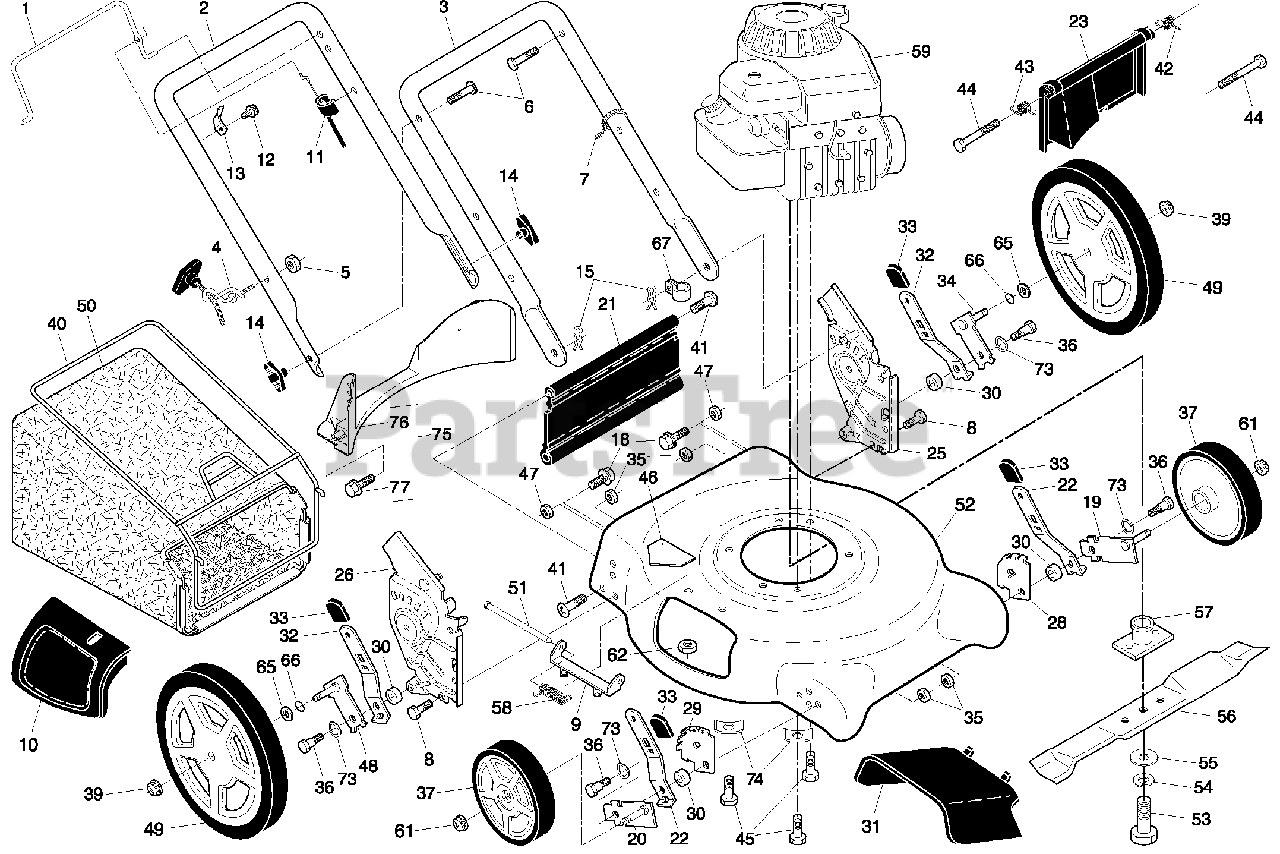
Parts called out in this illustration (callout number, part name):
1	Control Bar
2	Upper Handle
3	Lower Handle
4	Rope Guide
6	Handle Bolt
7	Wire Tie
8	Bolt
9	Hinge Bracket
10	Mulcher Door
11	Engine Zone Control Cable
12	Hex Washer Head Screw
13	Up-Stop Bracket
14	Handle Knob
15	Hairpin Cotter
18	Screw 1/4-20 x 3/8
19	Axle Arm Assembly, Front, LH
20	Axle Arm Assembly, Front, RH
21	Kit, Rear Skirt
22	Selector Spring, Front
23	Rear Door Assembly
25	Handle Bracket Assembly, LH
26	Handle Bracket Assembly, RH
28	Wheel Adjusting Bracket, Front, LH
29	Wheel Adjusting Bracket, Front, RH
30	Spacer
31	Discharge Deflector
32	Selector Spring, Rear
33	Selector Knob
34	Axle Arm Assembly, Rear, LH
35	Locknut, Hex 5/16-18
36	Shoulder Bolt 5/16-18
37	Wheel & Tire Assembly, Front, 7"
39	Locknut, Hex, Flanged
40	Frame, Grass Bag
41	Hinge Screw
42	Spring, Rear Door, LH
43	Spring, Rear Door, RH
44	Bolt, Rear Skirt
45	Hex Head Thread Rolling Screw 3/8-16 x 1
46	Danger Decal
47	Nut, Hex
48	Axle Arm Assembly, Rear, RH
49	Wheel & Tire Assembly, Rear, 12"
50	Grass Bag
51	Rod, Hinge
52	Housing Assembly
53	Hex Head Screw 3/8-24 x 1-3/8 Grade 8
54	Helical Lockwasher
55	Hardened Washer
56	21" Blade
57	Blade Adapter
58	Spring, Hinge
61	Locknut, Hex, Flanged
62	Locknut, Hex 1/4-20
65	Washer, Flat
66	O-Ring
67	Clip, Cable
73	Washer, Curved
74	Washer, Special, Engine
75	Kit, Rear Baffle
76	Baffle, Rear
77	Screw, Rear Baffle
